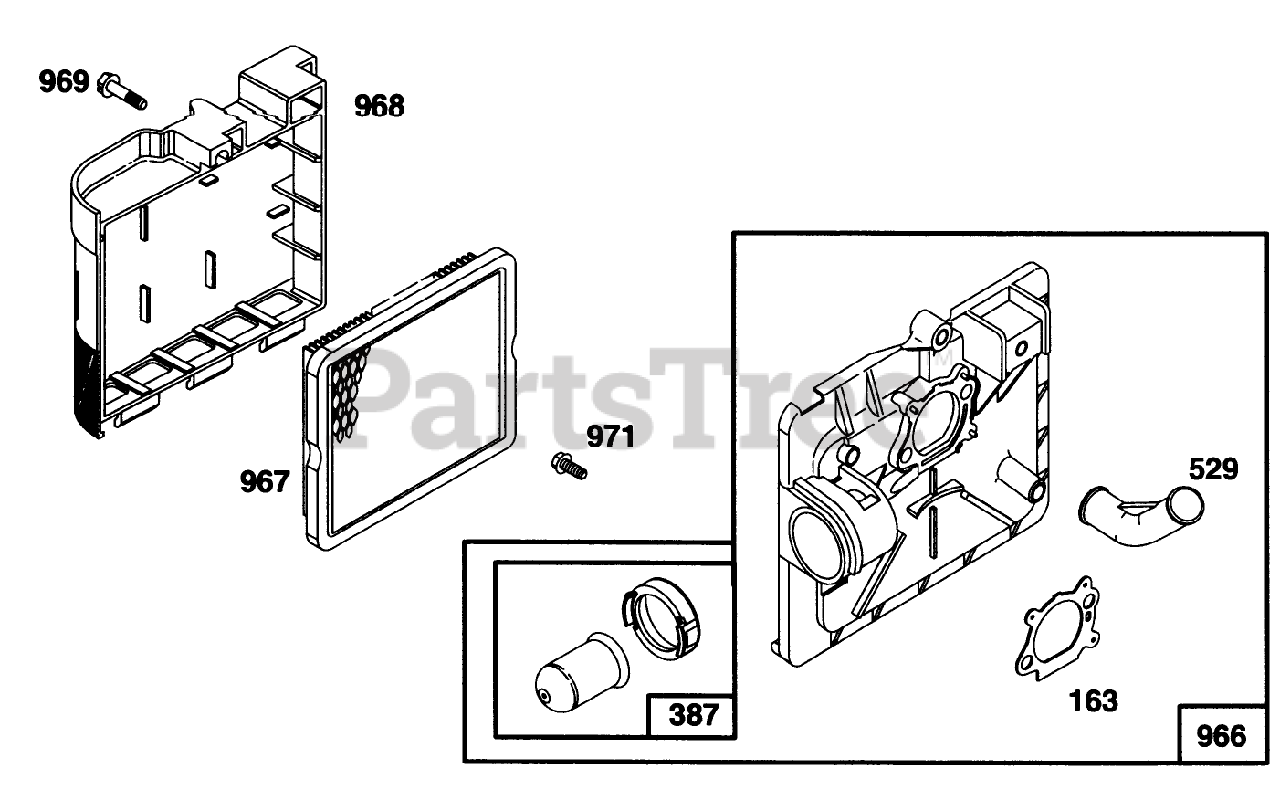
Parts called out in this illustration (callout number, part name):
163	Gasket-Cleaner, Air
387	CarburetorPrimer
529	Grommet
966	Base-Primer, Air Cleaner
967	Filter-Air Cleaner, Cartridge
968	Air Cleaner Cover
969	Screw-Cover Mt.
971	Screw-Air Cleaner
